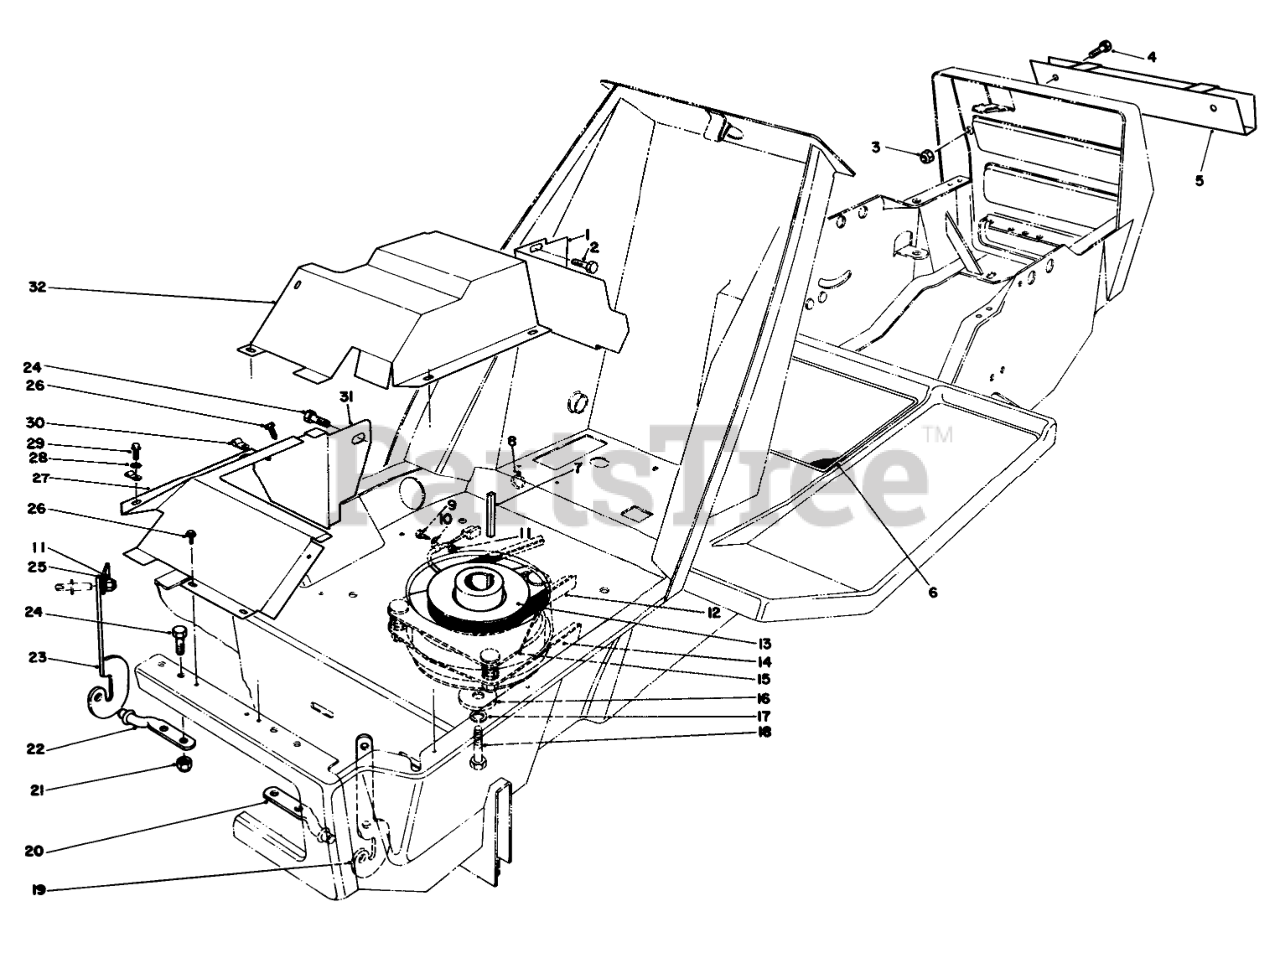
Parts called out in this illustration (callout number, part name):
1	EXH SHIELD SUPT B
2	SCREW-HH
3	NUT-LOCK, NI
4	SCREW-HH
5	ADAPTER CHANNEL WA B
6	OPERATION DECAL
7	KEY-SQUARE
8	TIE-MOUNT, PUSH
9	SCREW-HH
10	CLAMP
11	NUT-LOCK, NI
12	V BELT
13	Pulley
14	V BELT
15	Clutch Assembly-Deck
16	WASHER-CLUTCH
17	WASHER-LOCK
18	SCREW-HH
19	L.H. HINGE BRACKET
20	LH HOOD HINGE PIN
21	NUT-LOCK, CONE
22	RH HOOD HINGE PIN
23	RH HINGE BRKT
24	SCREW-HH
25	SCREEN SUPT BRKT
26	SCREW-HWHTF
27	Heat Shield
28	WASHER-FLAT
29	SCREW
30	CABLE CLAMP
31	Support Heat Shield
32	HEAT SHIELD WA B
